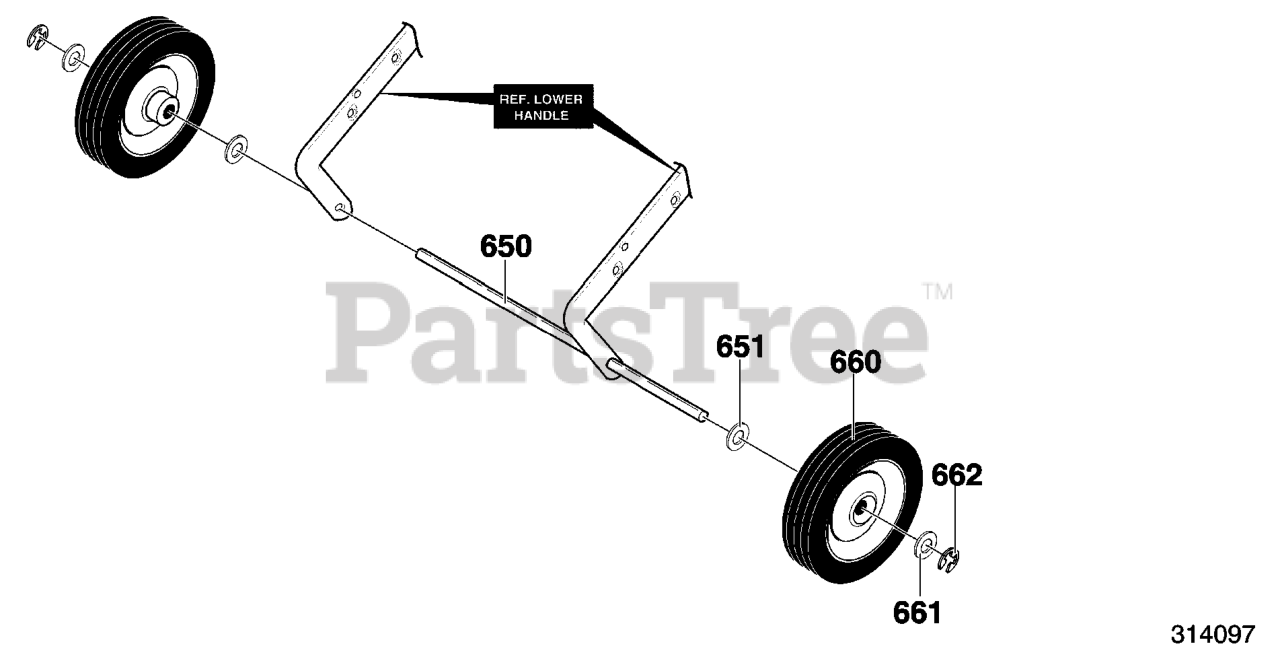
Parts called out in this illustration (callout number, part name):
650	AXLE SHAFT
651	WASHER, FLAT .391X1.00X1.25
660	TIRE & RIM
661	WASHER, FLAT .391X1.00X.125
662	RING, RET E
